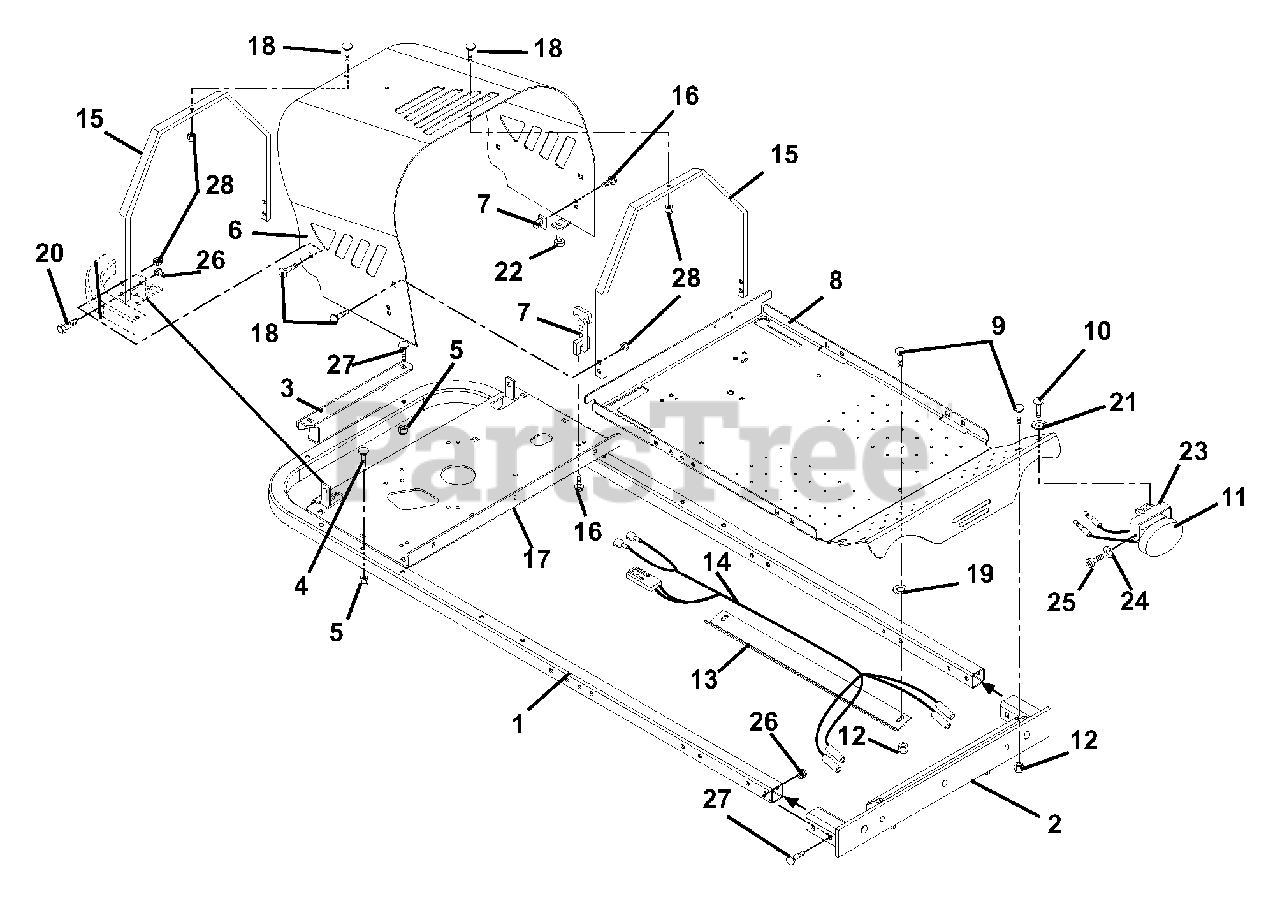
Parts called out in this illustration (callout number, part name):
1	TUBE-FRAME BLK
2	WMT, AXLE MOUNT
3	TRAILER HITCH W/DECALS
4	@BLT-RDHDSQNK .38-16X2.50 G5YZ
5	@NUT-LK-NYL-FLG .38-16 YWZC
6	HOOD, ZOOM
7	LATCH, RUBBER
8	FOOTREST
9	@BLT-RDHDSQNK .31-18X1.00 G5YZ
10	SCR-CAP BTHD.31-18X.50 GR5 YZ
11	LIGHT-CONS RIDE ON- SEE B-2124
12	@NUT-LK-NYL-FLG .31-18 YWZC
13	BKT-HARNESS
14	HARNESS, LIGHT
15	BRACE, HOOD
16	@SCR-MCH 10-24X.50 HWH YWZC
17	PLATE, ENGINE
18	@BLT-RHDSSQNK .31-18X.62 G5YZ
19	WSHR-FL-STL .328X.87X.179 YWZC
20	BOLT-SHLDR .375-16X.150
21	@WSHR-LK .31X.078 REG YWZC
22	BUTTON BUMPER
23	WMT, LIGHT BRACKET
24	WSHR-LK 4MMX1MM REG CL ZINC
25	SCREW-M4X.07X8 SHCS CLZNC
26	@NUT-LK-TOP-FLG .38-16 YWZC
27	@BLT-RDHDSQNK .38-16X2.25 G5YZ
28	@NUT-LK-TOP-FLG .31-18 YWZC
